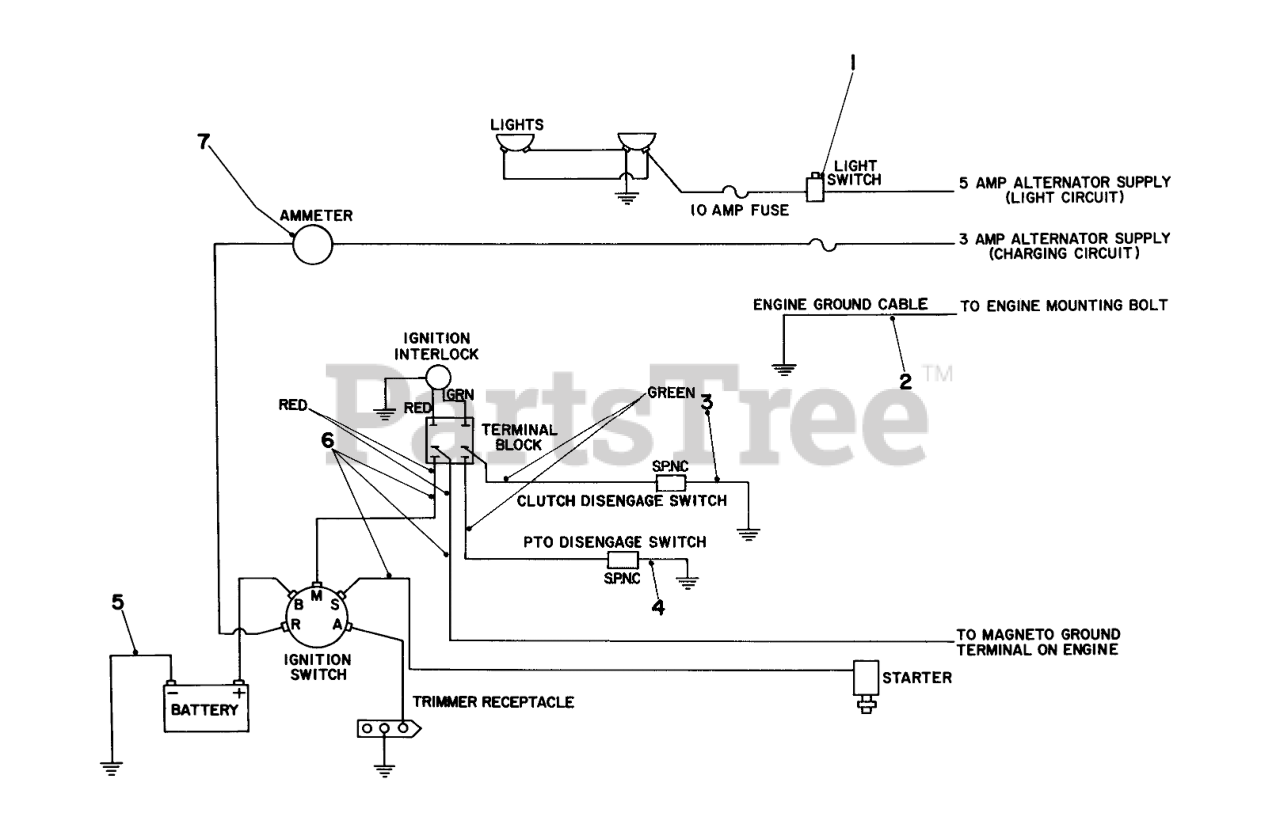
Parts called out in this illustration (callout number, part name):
1	Light Switch
2	ENG-GROUND WIRE ASM
3	Wire Assembly
4	Wire Assembly
5	Wire Assembly
6	Wire Harness
7	Ammeter
